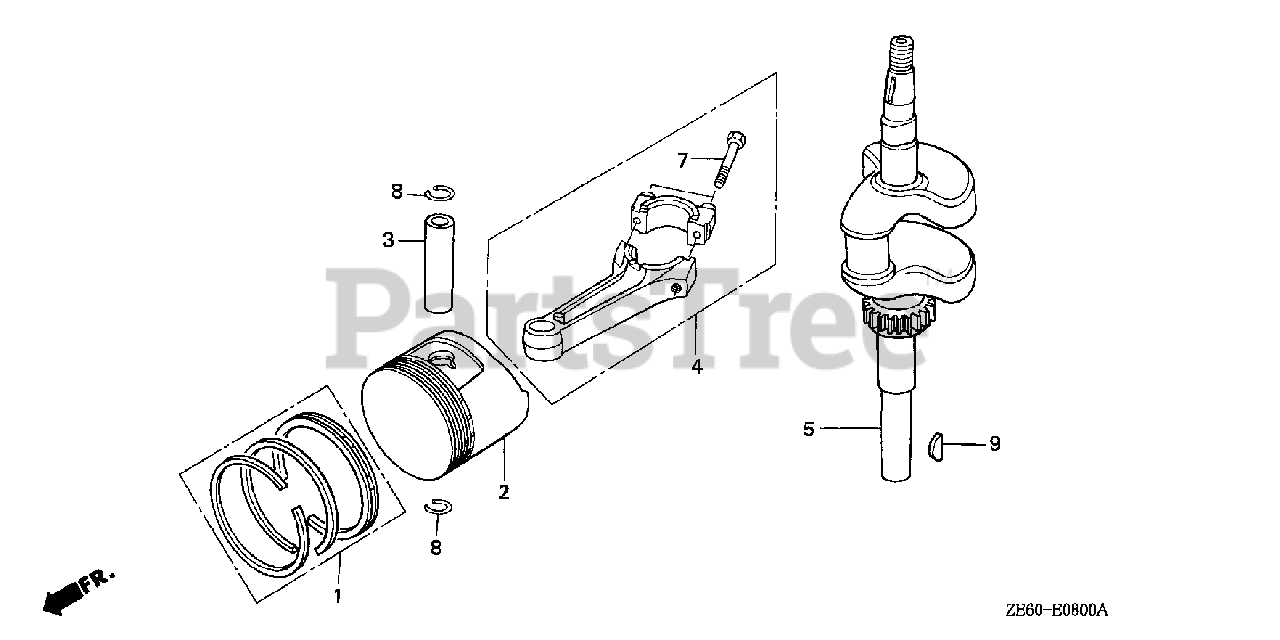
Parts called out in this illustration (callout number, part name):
1	RING SET, PISTON (STD) (NIPPON)
1	RING SET, PISTON (0.25) (NIPPON)
1	RING SET, PISTON (0.50) (NIPPON)
1	RING SET, PISTON (0.75) (NIPPON)
2	PISTON (STD)
2	PISTON (0.25)
2	PISTON (0.50)
2	PISTON (0.75)
3	PIN, PISTON
4	ROD ASSY., CONNECTING
4	ROD ASSY., CONNECTING (0.25 LOWER SIZE)
5	CRANKSHAFT
7	BOLT, CONNECTING ROD
8	CLIP, PISTON PIN (13MM)
